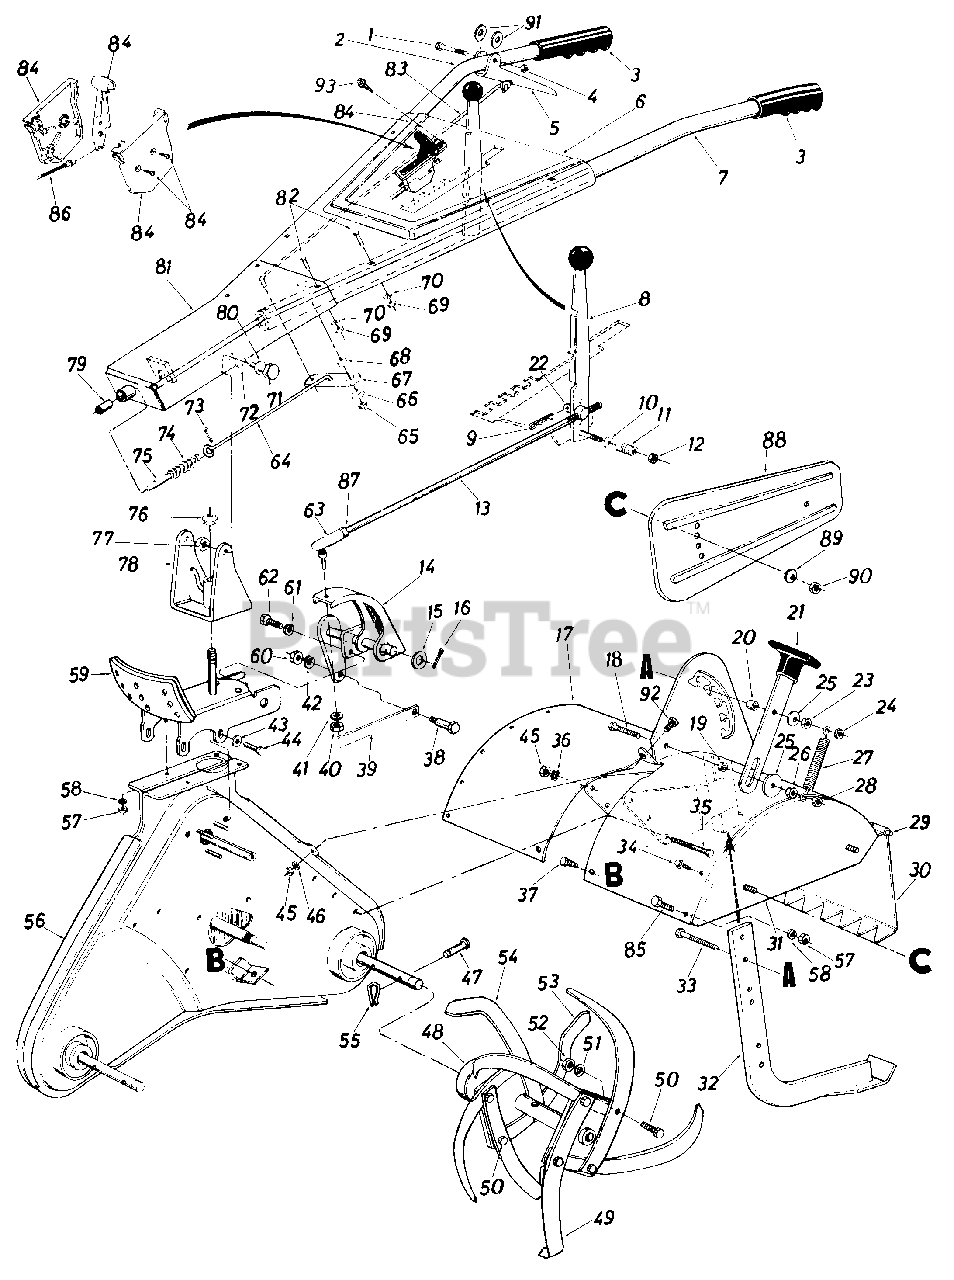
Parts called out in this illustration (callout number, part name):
1	Hex Bolt 1/4-20 x 1.75" Lg.*
2	Handle-R.H.
3	Grip
4	Hex Cent. L-Nut 1/4-20 Thd.
5	Clutch Grip
6	Handle Panel Ass'y.
7	Handle-L.H.
8	Clutch Handle Ass'y.
9	Hairpin Cotter
10	Belleville Wash. .38" I.D.
11	Compression Spring .88" O.D. x .81" Lg.
12	Hex Cent. L-Nut 3/8-24 Thd.
13	Gear Shift Rod
14	Pivot Horn Ass'y.
15	Fl-Wash. .630 I.D. x 1.0" O.D. x .063
16	Cotter Pin 1/8" Dia. x .75" Lg. *
17	Tine Shield Ass'y.
18	Hex Bolt 3/8-16 x 1.5" Lg.
19	Spacer .38 I.D. x .50 O.D. x .18 Lg.
20	Spacer .38 I.D. x .50 O.D. x .38 Lg.
21	Depth Bar Handle Ass'y. w/Knob
22	Ferrule
23	Hex Nut 3/8-16 Thd.*
24	Hex Ins. L-Nut 3/8-16 Thd.
25	Fl-Wash. .38 I.D. x 1.50 O.D. x .13
26	Hex Nut 3/8-16 Thd.*
27	Spring-Depth Bar
28	Hex Ins. L-Nut 3/8-16 Thd.
29	Hinge Rod
30	Tine Shield Hinge Flap Ass'y.
31	Side Cover Tine Shield-L.H.
32	Depth/Drag Bar Ass'y.
33	Hex Bolt 3/8-16 x 1.75" Lg.*
34	Hex Wash. Hd. Self-Tap Scr. 5/16-18 x .62" Lg.
35	Hex Bolt 3/8-24 x 3.0" Lg.
36	L-Wash. 3/8" I.D.*
37	Hex Wash. Hd. Self-Tap Scr.
38	Shoulder Bolt .50" Dia. x .25" Lg.
39	Control Bracket
40	Hex Ins. L-Nut 3/8-24 Thd.
41	L-Wash. 318" I.D.*
42	L-Wash. 318" I.D.*
43	Belleville Wash.
44	Hex Wash. Hd. Self-TaP Scr.
45	Hex Nut 3/8-24 Thd.*
46	L-Wash. 3/8" Scr.*
47	Clevis Pin
48	Tine Adapter Ass'y.
49	L.H. Tine Ass'y. Comp.
50	Hex Bolt 3/8-24 x 1.25" Lg.*
51	L-Wash. 3/8" I.D.*
52	Hex Nut 3/8-24 Thd.*
54	Tine-L.H.
55	Hairpin Cotter
56	Chain Case Ass'y. Comp.
57	Hex Nut 5/16-18 Thd.*
58	L-Wash. 5/16" I.D.*
59	Handle Positioner Ass'y.
60	Hex Ins. L-Nut 3/8-16 Thd.
61	L-Wash. 5/16" I.D.*
62	Hex Wash. Hd. Self-Tap Scr.
63	Rod End 3/8-24 Thd.
64	Lower Handle Control Rod
65	Hex Nut 5/16-18 Thd.*
66	Pivot Handle Brg.
67	Pivot Handle Link
68	Bushing Wash.
69	Hex Nut 5/16-18 Thd.*
70	L-Wash. 5/16" I.D.*
71	Shld. Bolt .500" Dia. x .660
72	Belleville Wash. .505" I.D. x 1.00" O.D.
73	Cotter Pin 118" Dia. x .75" Lg. *
74	Compression Spring
75	Locking Pin
76	Hex Ins. L-Nut 5/8-16 Thd.
77	Hex Top L-Nut 3/8-16 Thd.
78	Pivot Brkt. Ass'y.
79	Sleeve Brg. .50" l.D. x .62" O.D. x 1.12" Lg.
80	Fl-Wash. .50" I.D. x 1.00" O.D. x .090
81	Handle Mtg. Brkt. Ass'y.
82	Carriage Bolt 5/16-18 x 1.75" Lg.*
83	Handle Lock Rod
84	Throttle Control Box Ass'y.
85	Hex Bolt 5/16-18 x .75" Lg.*
86	Throttle Control Wire
87	Hex Jam Nut 3/8-24 Thd.
90	Hex Nut 5/16-18 Thd.
91	Fl-Wash. 1/4" l.D.
92	Hex Bolt 3/8-24 x .75" Lg.
93	Self-Tap Scr. #10 x 1/2" Lg.
